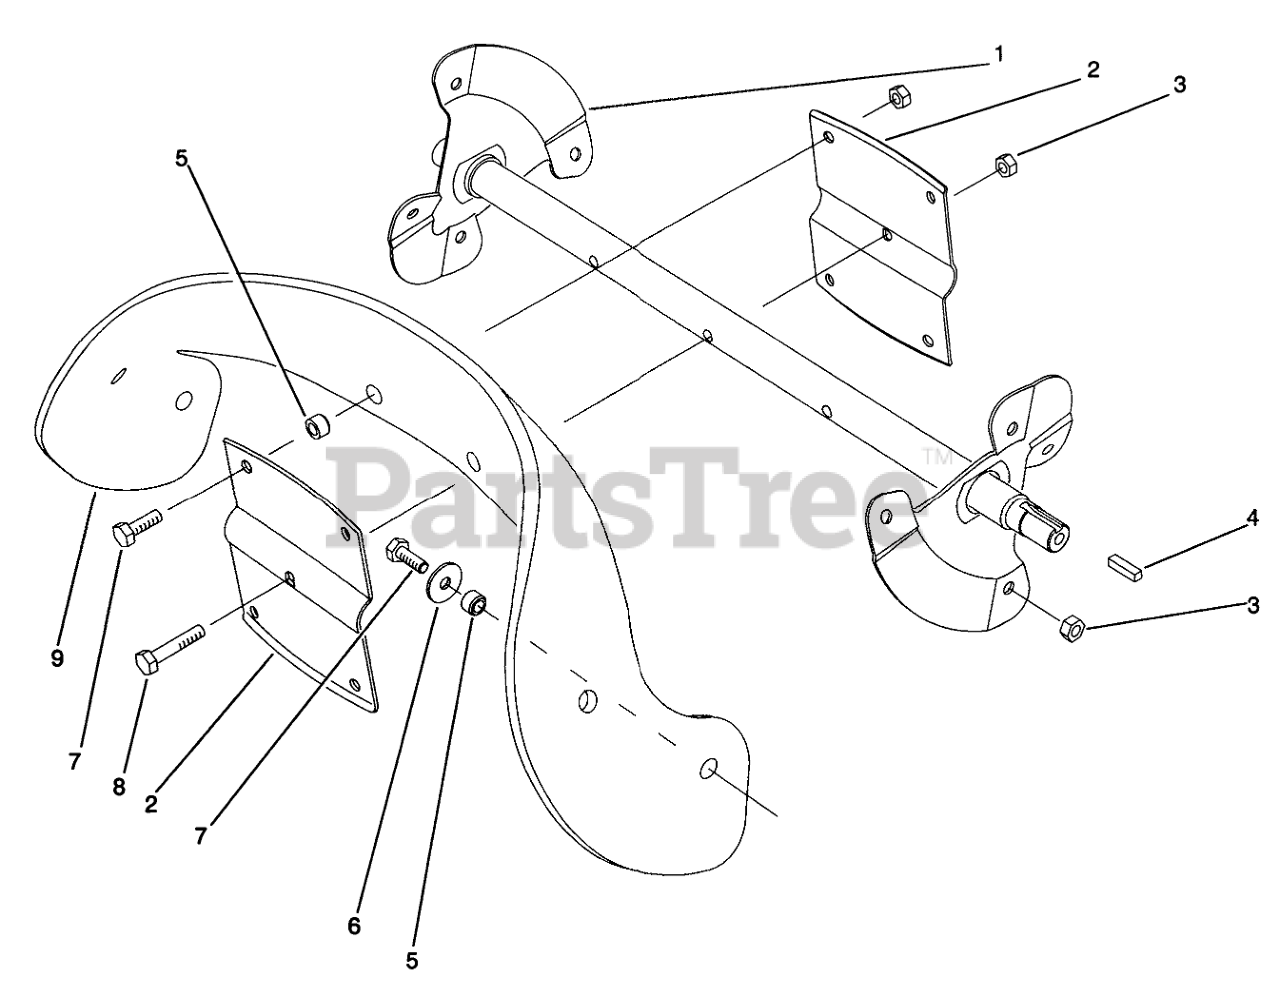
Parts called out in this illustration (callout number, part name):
1	Rotor Shaft Assembly
2	Rotor
3	NUT-LOCK, NI
4	KEY-SQUARE
5	SPACER-BLADE, ROTOR
6	WASHER-FLAT
7	SCREW-HH
8	SCREW-HH
9	Blade-Rotor
